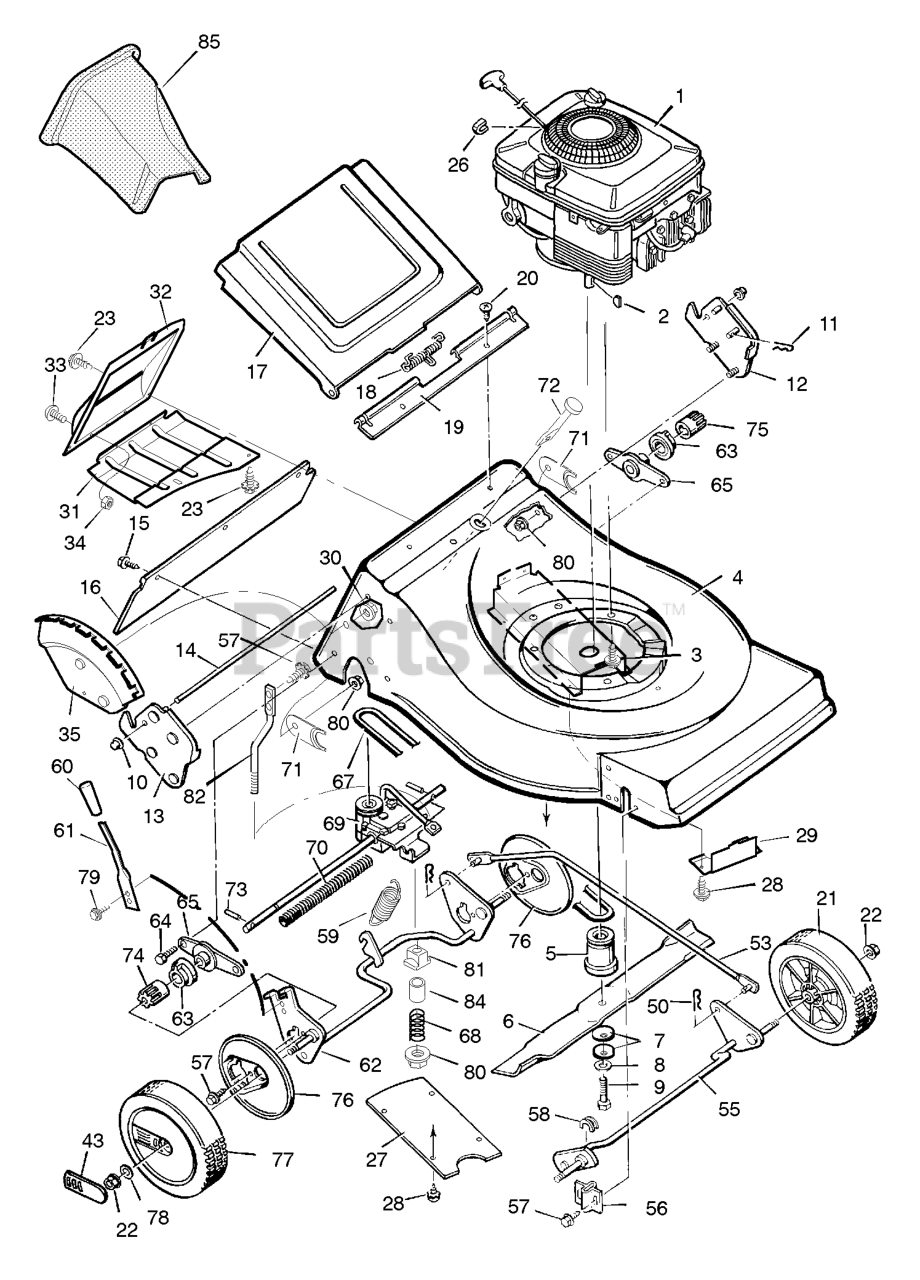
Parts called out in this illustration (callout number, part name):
1	Engine *
2	Key, Woodruff
3	Bolt, Engine
4	Housing
5	Adapter, Blade
7	Washer, Belleville
10	Push On Cap
11	Pin, Hair
12	Handle Bracket, Left
13	Handle Bracket, Right
14	Rod, Door Pivot
16	Deflector, Rear
17	Door, Rear
18	Spring, Torsion
19	Spacer, Door
21	WHEEL & TIRE ASSEMBLY, White, 8"
22	Nut
26	Stop, Rope
27	Cover, Belt
29	Cover, Front Belt
30	Nut, Hex Flange
31	Cover, Lower
32	Cover, Rear
33	Screw
35	Bracket, Index
43	Hub Cap
50	Pin, Hair
53	Link, Lifter
55	Crossbar, Front
56	Clip, Retainer
58	Bushing
59	Spring, Extension
60	Grip, Height Adjuster
61	Lever, Height Adjuster
62	Crossbar, Rear
63	Bearing, Lifter
64	Bolt, Hex
65	Support, Axle
67	Belt, Drive
68	Spring
69	Transmission TIM .50
70	Shield, Axle
71	Retainer, Bearing
72	Support, Lifter Spring
73	Pin, Drive
74	Pinion, Right
75	Pinion, Left
76	Cover, Dust
77	Wheel, Drive - White
78	Washer, Thrust
80	Locknut
81	Bushing
82	Support, Spring
85	Plug, Mulcher
